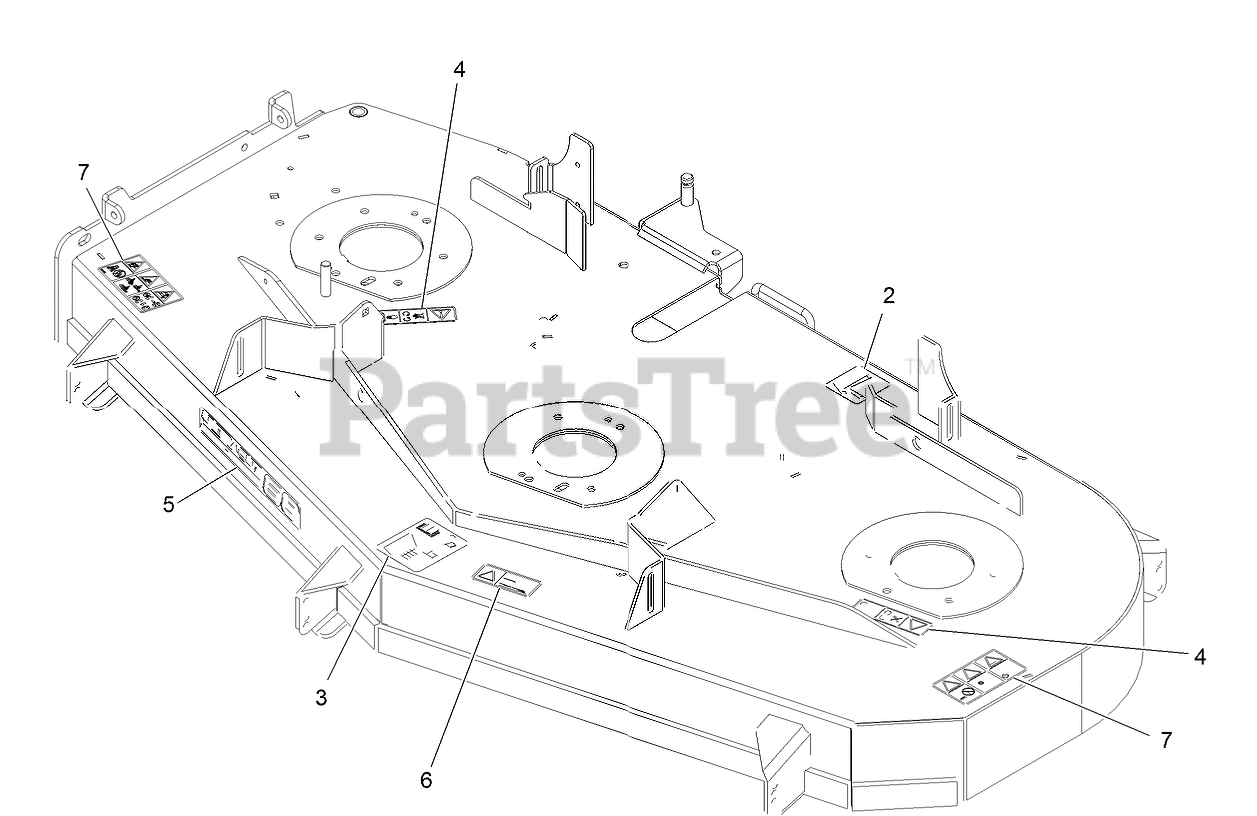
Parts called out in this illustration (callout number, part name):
2	DECAL-ROUTING, BELT
3	DECAL-ROLLER, ANTI-SCALP
4	DECAL-COVER, MISSING
5	DECAL-ULTRACUT 60 SERIES
6	DECAL-BOLT TORQUE
7	DECAL-DANGER THROWN OBJECTS
